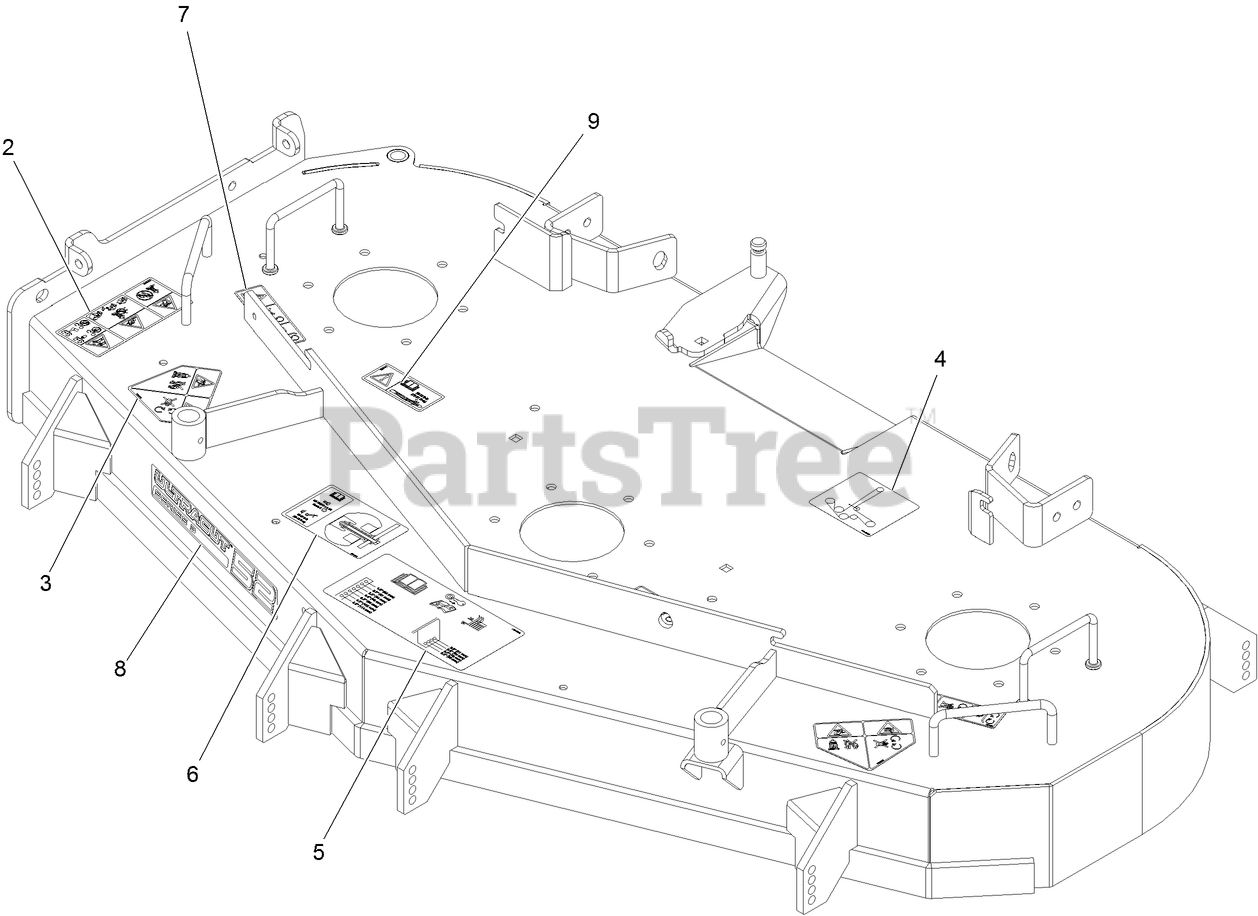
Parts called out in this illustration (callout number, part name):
2	DECAL-WARNING THROWN OBJ
3	DECAL-DANGER
4	DECAL-BELT ROUTING
5	DECAL-ANTI-SCALP
6	DECAL-ROLLER MOUNTING
7	DECAL-COVER, MISSING
8	DECAL-ULTRACUT 52 SERIES 3
9	DECAL-TORQUE, BOLT
